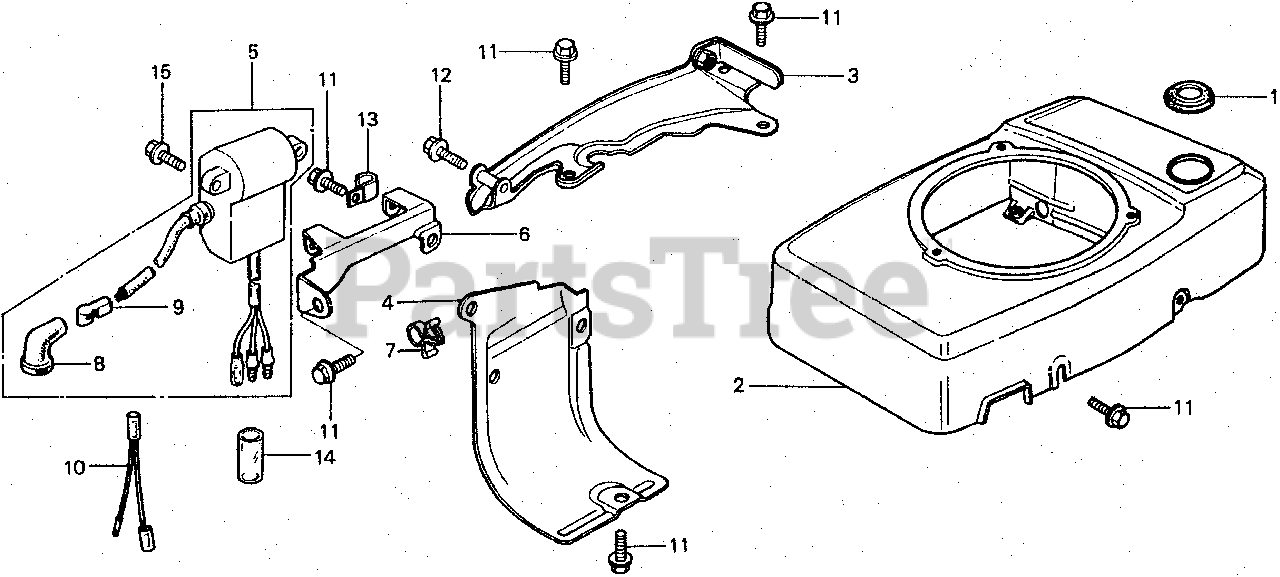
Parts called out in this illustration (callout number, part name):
1	SEAL, FILLER NECK
2	COVER, FAN *R8* (BRIGHT RED)
3	PLATE, SIDE
7	CLIP, IGNITION WIRE (8MM)
11	BOLT, FLANGE (6X12) (CT200)
12	BOLT, FLANGE (6X32)
14	TUBE, WIRE
